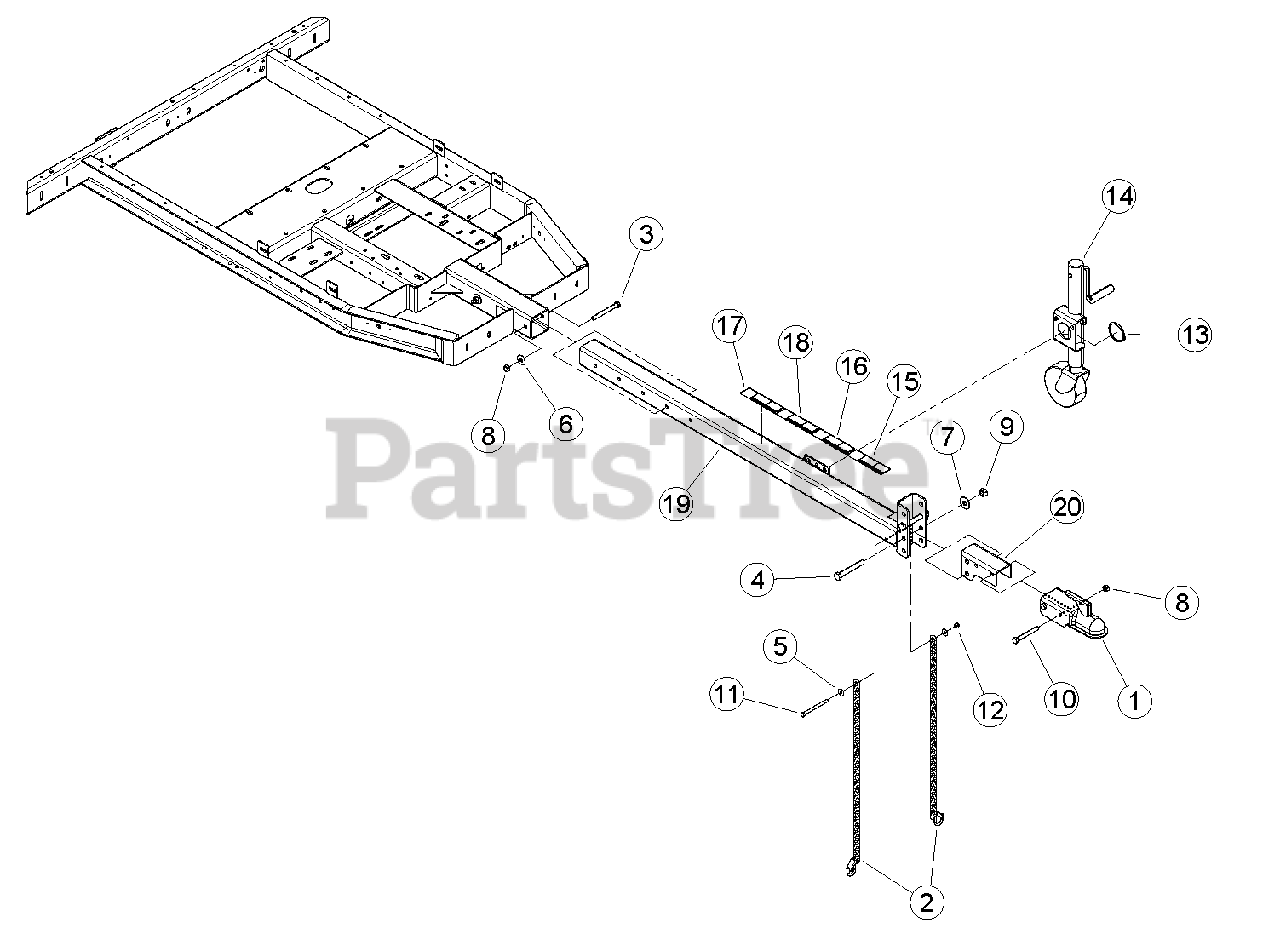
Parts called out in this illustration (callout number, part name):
1	COUPLER, 2 IN
2	CHAIN, SAFETY, 5000 LB W/LATCH
3	BOLT, 1/2 X 4-1/2 HEX HD GR5
4	BOLT, 5/8 X 4-1/2 HEX HD GR5
5	WASHER, 3/8 FLAT ZP
6	WASHER, 1/2 FLAT ZP
7	WASHER, 5/8 FLAT ZP
8	NUT, 1/2 CENTERLOCK GRB ZP
9	NUT, 5/8 CENTERLOCK
10	BOLT, 1/2 X 4 HEX GR5 ZP
11	BOLT, 3/8 NC X 4-1/2 HEX HD
12	NUT, 3/8 NYLOCK
13	SNAP RING, 2-1/2 EXTERNAL
14	JACK, PIVOTING W/SWIVEL CASTOR
15	DECAL, SAFETY CHAINS
16	DECAL, TRAILER ELECTRICAL
17	DECAL, CHECK WHEELS
18	DECAL, SAFE COUPLING
19	WELDMENT, HITCH POLE W/PLATE
20	MOUNT, COUPLER
